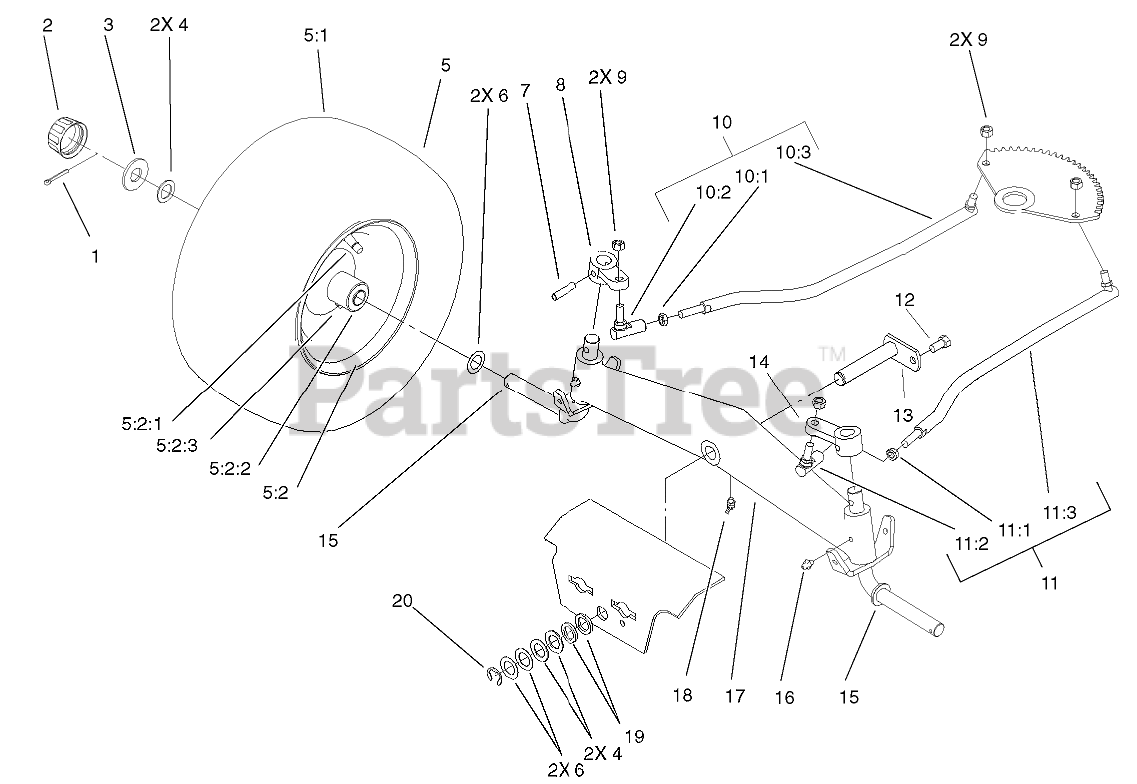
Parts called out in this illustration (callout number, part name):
1	PIN-COTTER
2	CAP-HUB
3	WASHER-PLAIN
4	WASHER
5	FRONT WHEEL & TIRE ASM
5:2	Wheel ASM
5:2:1	VALVE
5:2:2	BEARING-WHEEL
5:2:3	ZERK-GREASE
6	WASHER-SHIM
8	Arm-Front Spindle
10	LINKAGE-STEERING, RH
10:1	NUT-JAM
10:2	BALL-JOINT
10:3	Ball Link ASM
11	LINKAGE-STEERING, LH
11:1	NUT-JAM
11:2	BALL-JOINT
11:3	Ball Link ASM
12	SCREW-HWH, TAPTITE
13	PIN-AXLE
14	Arm-Front Spindle
15	SPINDLE
16	FITTING-GREASE
17	AXLE-FRONT
18	FITTING-LUBE, 45 DEG
19	Washer
20	E-RING
